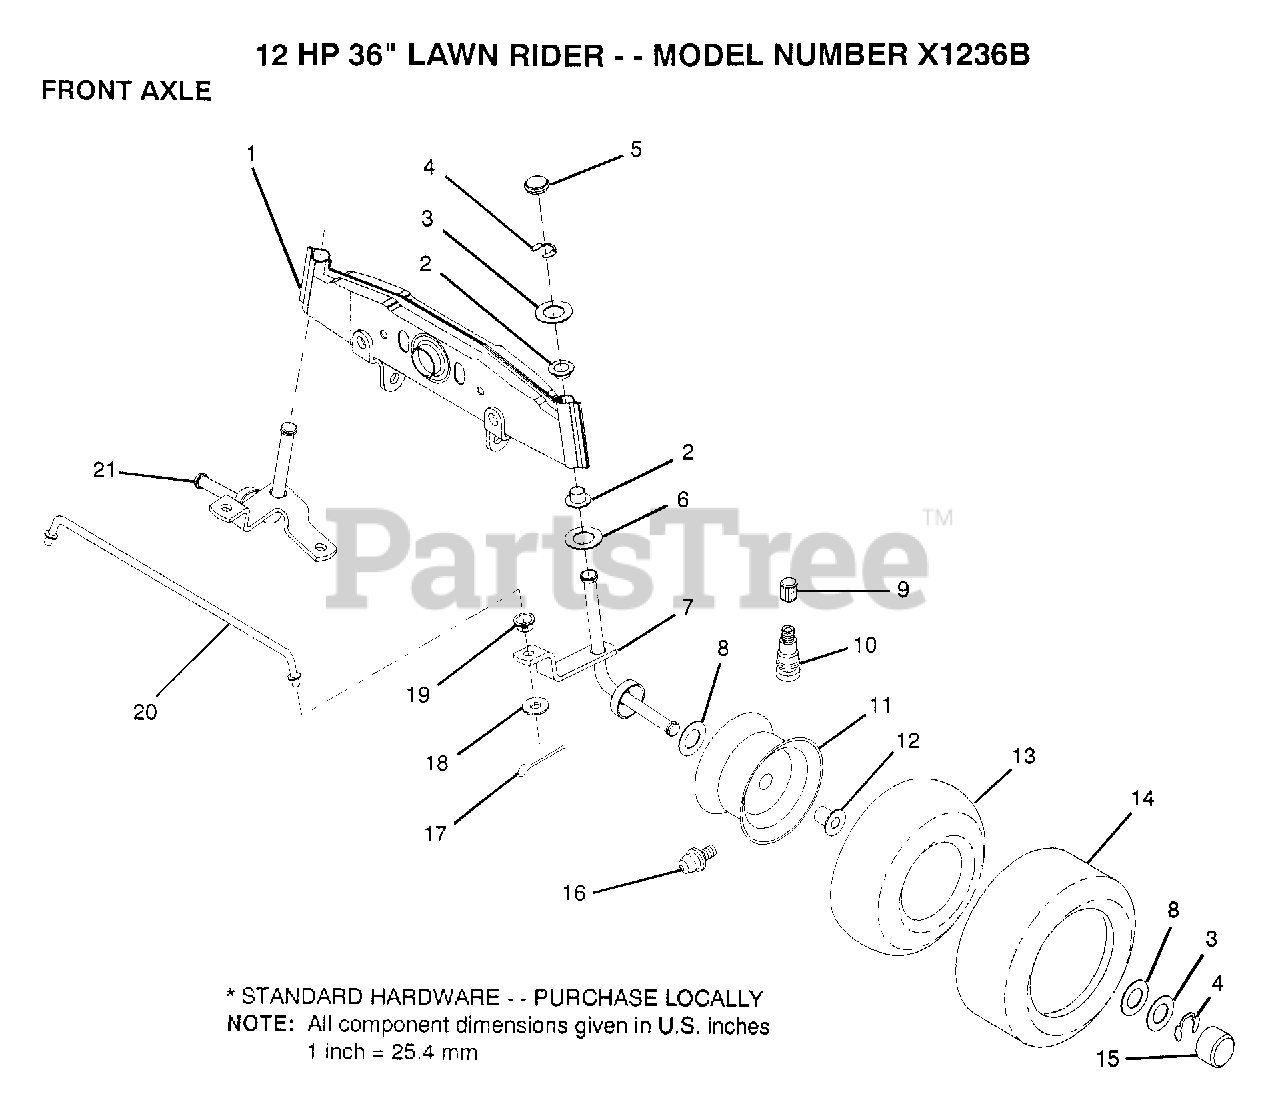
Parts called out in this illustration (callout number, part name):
2	NYLINER
3	WASHER
4	RING
5	CAP
6	WASHER .T
7	SPINDLE RH
8	WASHER
9	VALVE CAP
10	VALVE STEM LT
12	"FLANGE, BEARING"
13	TUBE.5.3/4.5/6
14	TIRE
15	HUB CAP
16	FITTING LT
17	COTTER PIN
18	WASHER
19	BUSHING.DRAGLINK
20	ROD TIE
21	SPINDLE LH
